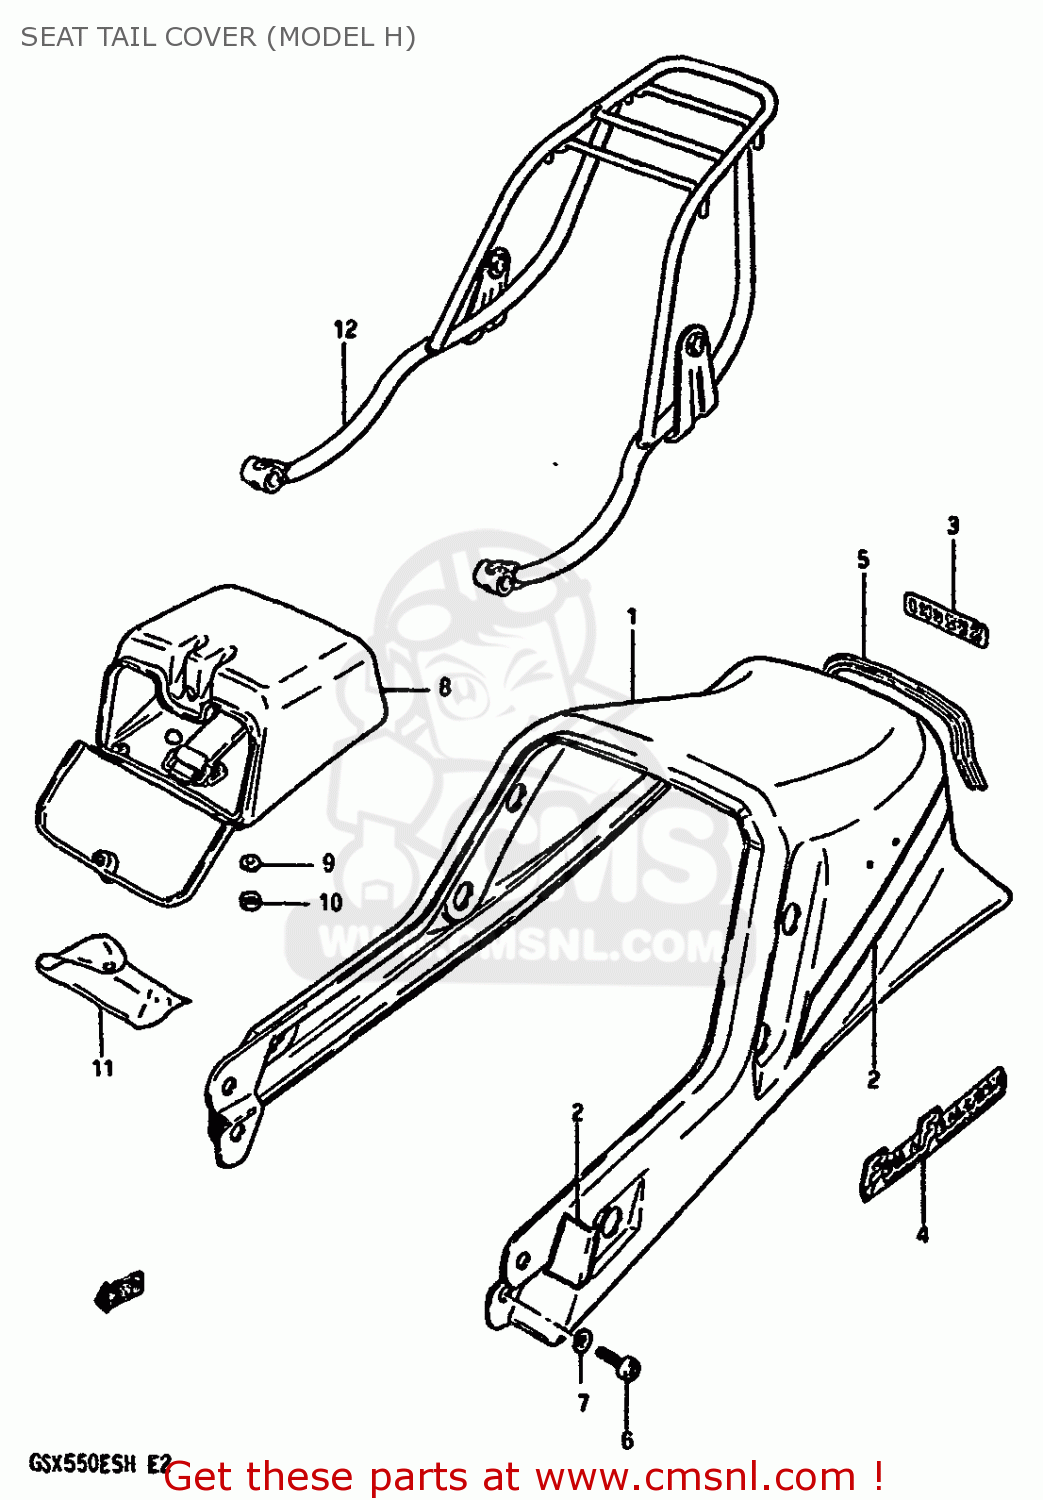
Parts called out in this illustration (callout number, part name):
1	COVER,SEAT TAIL
2	TAPE SET,TAIL COVER
3	EMBLEM
4	EMBLEM
5	BLIND,SEAT TAIL COVER
6	SCREW
7	WASHER,LOCK
8	BOX,SEAT TAIL
9	WASHER
10	NUT
11	TOOL ASSY
12	CARRIER, SPORTS
